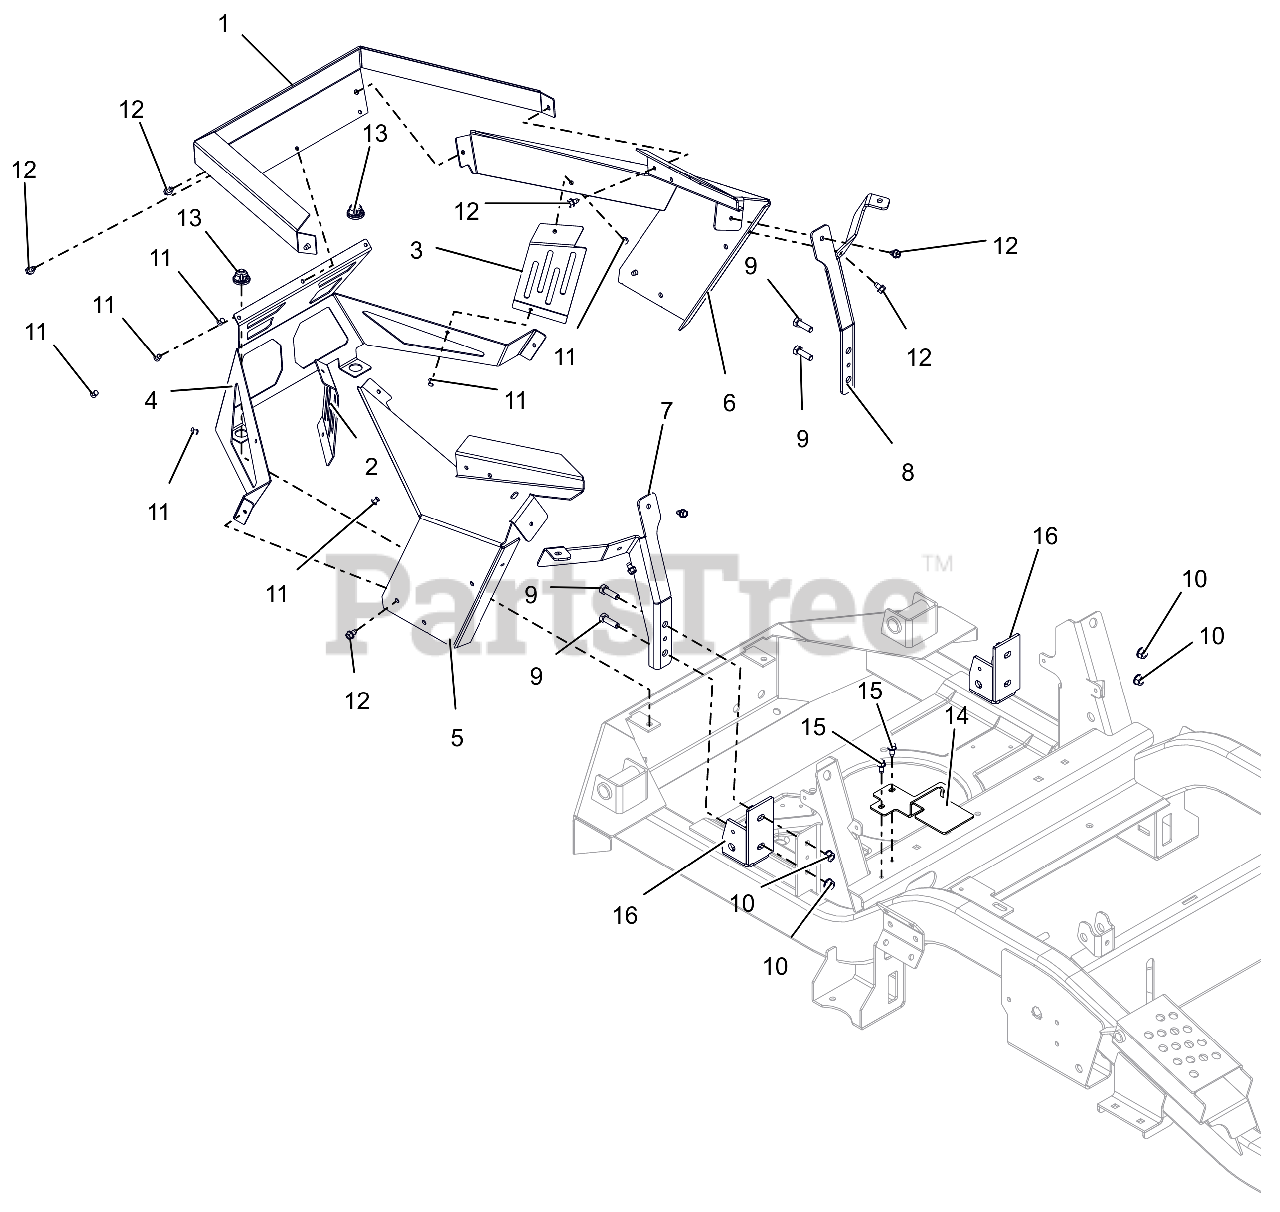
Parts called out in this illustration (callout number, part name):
1	GUARD,ENGINE WRAP
2	SHIELD,RH ENGINE GUARD VALVE
3	SHIELD,LH ENGINE GUARD VALVE
4	GUARD, ENGINE
5	PANEL, RH REAR FENDER MOUNT
6	PANEL, LH REAR FENDER MOUNT
7	BRKT, RH FENDER MTG (ORANGE)
8	BRKT, LH FENDER MOUNT (ORANGE)
9	BLT, HEX .31-18X1.00 G8 ZCC
10	NUT,LK-CTR-FLG .31-18 GF ZCC
11	RIVET, .1875 AL/AL .126-.250
12	SCR,TAP .25-20X.375 HWH TR ZCC
13	GROMMET, 10MM BOLLHOFF
14	GUARD, TRANSAXLE FAN RH (BLACK)
15	SCR-TAP .25-20X.50 HWH ZCC
16	BRKT, ROPS SUPPORT (BLACK)
